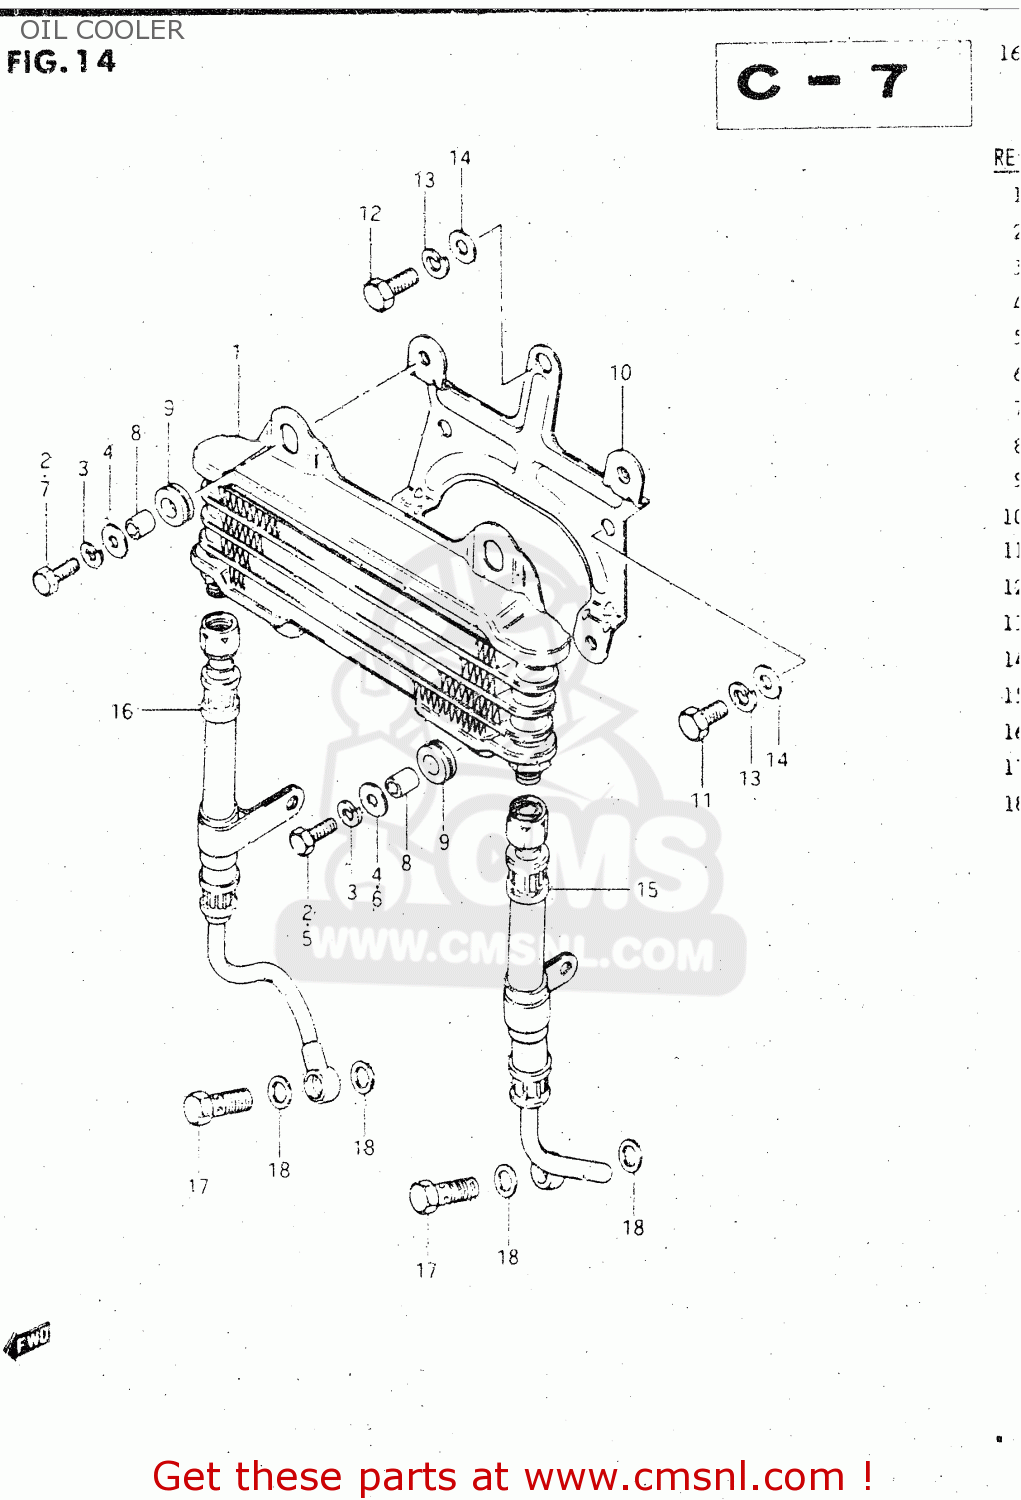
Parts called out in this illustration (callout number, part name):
1	COOLER ASSEMBLY,ENGINE OIL
2	BOLT
3	LOCK WASHER
4	WASHER (6.5X18X1.6)
5	BOLT
6	WASHER (6.5X18X1.6)
7	BOLT
8	SPACER (6.8X10X10)
9	CUSHION
10	BRACKET,OIL COOLER
11	BOLT
12	BOLT
13	WASHER,LOCK,8.
14	WASHER,8.5X16X
15	HOSE,ENGINE OIL,LEFT
16	HOSE,ENGINE OIL,RIGHT
17	BOLT UNION
18	GASKET(14X20X1.5) (NAS)
